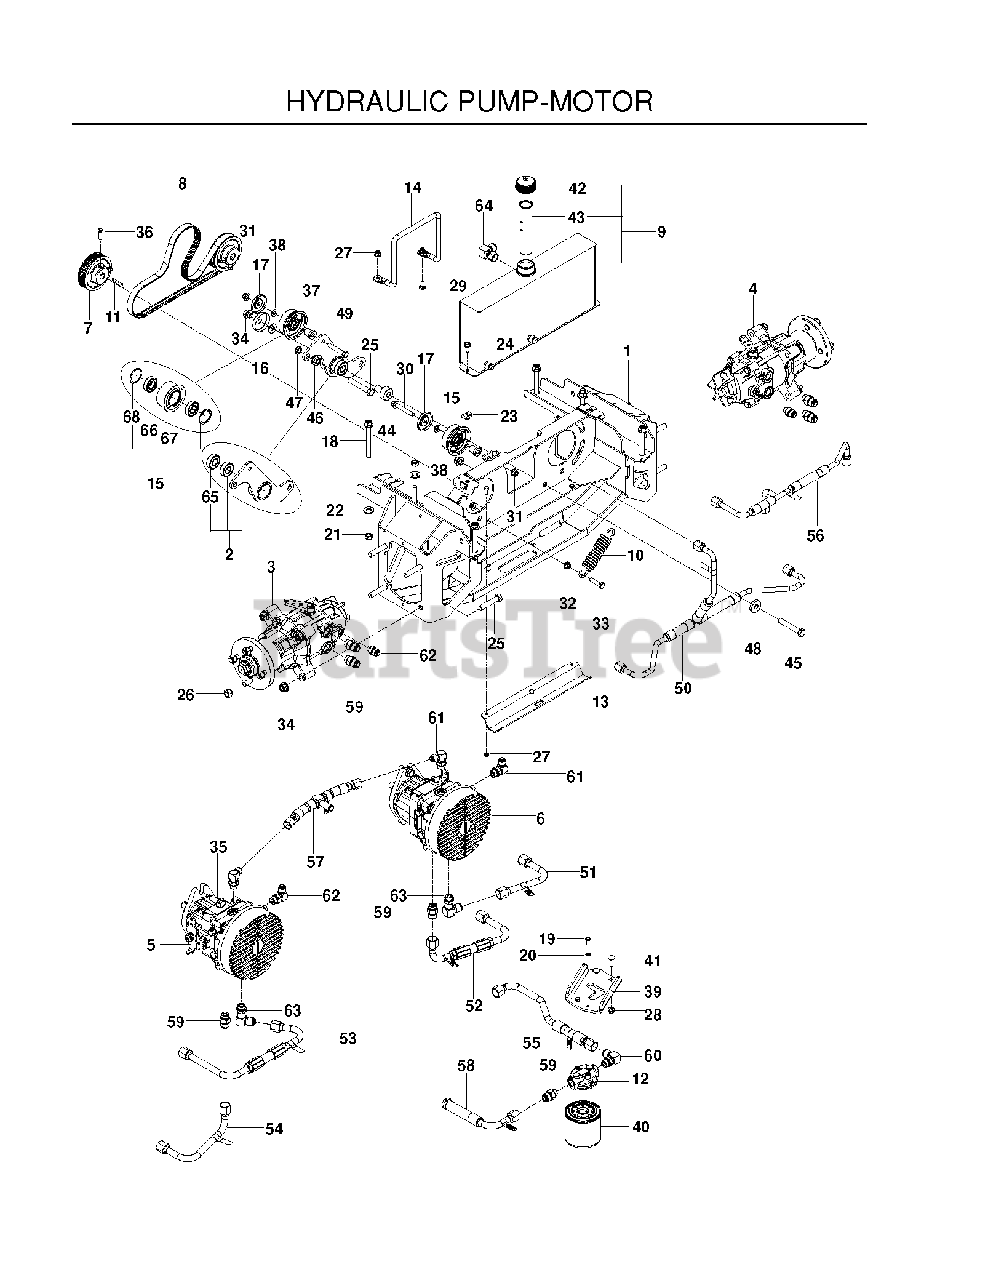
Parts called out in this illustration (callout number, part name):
1	WELDMENT, PUMP BAY, BLK
2	ASSEMBLY, IDLER W/BEARINGS
3	MOTOR, PRM, RT
4	MOTOR, PRM, LT
5	PUMP, 21CC, RT
6	PUMP, 21CC, LT
7	PUMP SHEAVE
8	BELT, PUMP
9	ASSEMBLY, RESERVOIR
11	KEY, METRIC
12	FILTER HEAD
16	SHIELD, DUST
17	DUST SHIELD
18	BOLT 7/16 X 4 GR 8 BLK PHOS
19	HCS 1/4C X 5/8
20	LOCKWASHER 1/4"
21	7/16-14 HEX NUT W/NYLOC
22	WASHER 1/2" FLAT
23	U-CLIP 5/16-18 NUT RETAINER
24	HHFS 5/16-18 X 3/4
25	HEX SCREW 3/18-16 X 3.5" G5
26	LUG NUT 1/2F
27	JAM NUT 1/4C
28	5/16-18 NYLOC FLANGE NUT
29	BOLT 5/16C X 3/4" CARRIAGE
30	HHFS 3/8-16 X 2 3/4
31	NUT 3/8-16 HEX FLG NYLOC ZD
32	NUT 3/8C WHIZ
33	HCS 3/8-16 X 1-1/2
34	NUT, 1/2-13 HEX FLG NYLOC ZD
35	HCS 1/2C X 1 1/4 SERRATED HEAD
36	SCREW 5/16C X 1 SQ HEAD SET
37	SPACER, IDLER
38	WASHER 3/8 SAE FLAT
39	MOUNT, FILTER, BLK
40	FILTER 25 MICRON
41	RHSNB 5/16C X 1
42	CAP, HYDRAULIC
43	TUBE, ANTI-SPLASH
44	PIVOT, BEARING
45	SCREW, 1/2C X 3 HEX CAP
46	NUT 1/2-13 HEX
47	NUT, HEX 1/2-13 THIN W/NY
48	WASHER.525X1.375X.25
49	HCS 3/8C X 2
50	LINE, HYD, CASE-RM
51	LINE, HYD, LT-AA
52	LINE, HYD, LT-BB
53	LINE, HYD, RT-AB
54	LINE, HYD, RT-BA
55	LINE, HYD, SUCTION
56	LINE, HYD, PUMP
57	LINE, HYD, CHARGE
58	LINE, HYD, CHARGE
59	FITTING, 10-8 STRAIGHT
61	ELBOW, 90 DEGREE
62	FITTING, HYDRO
63	FITTING, 10-8 90 DEG
64	FITTING, HYD, 6500-10-8
65	BEARING, BALL
66	BEARING
67	IDLER, PUMP
68	RING, RETAINING, 1-5/8"
